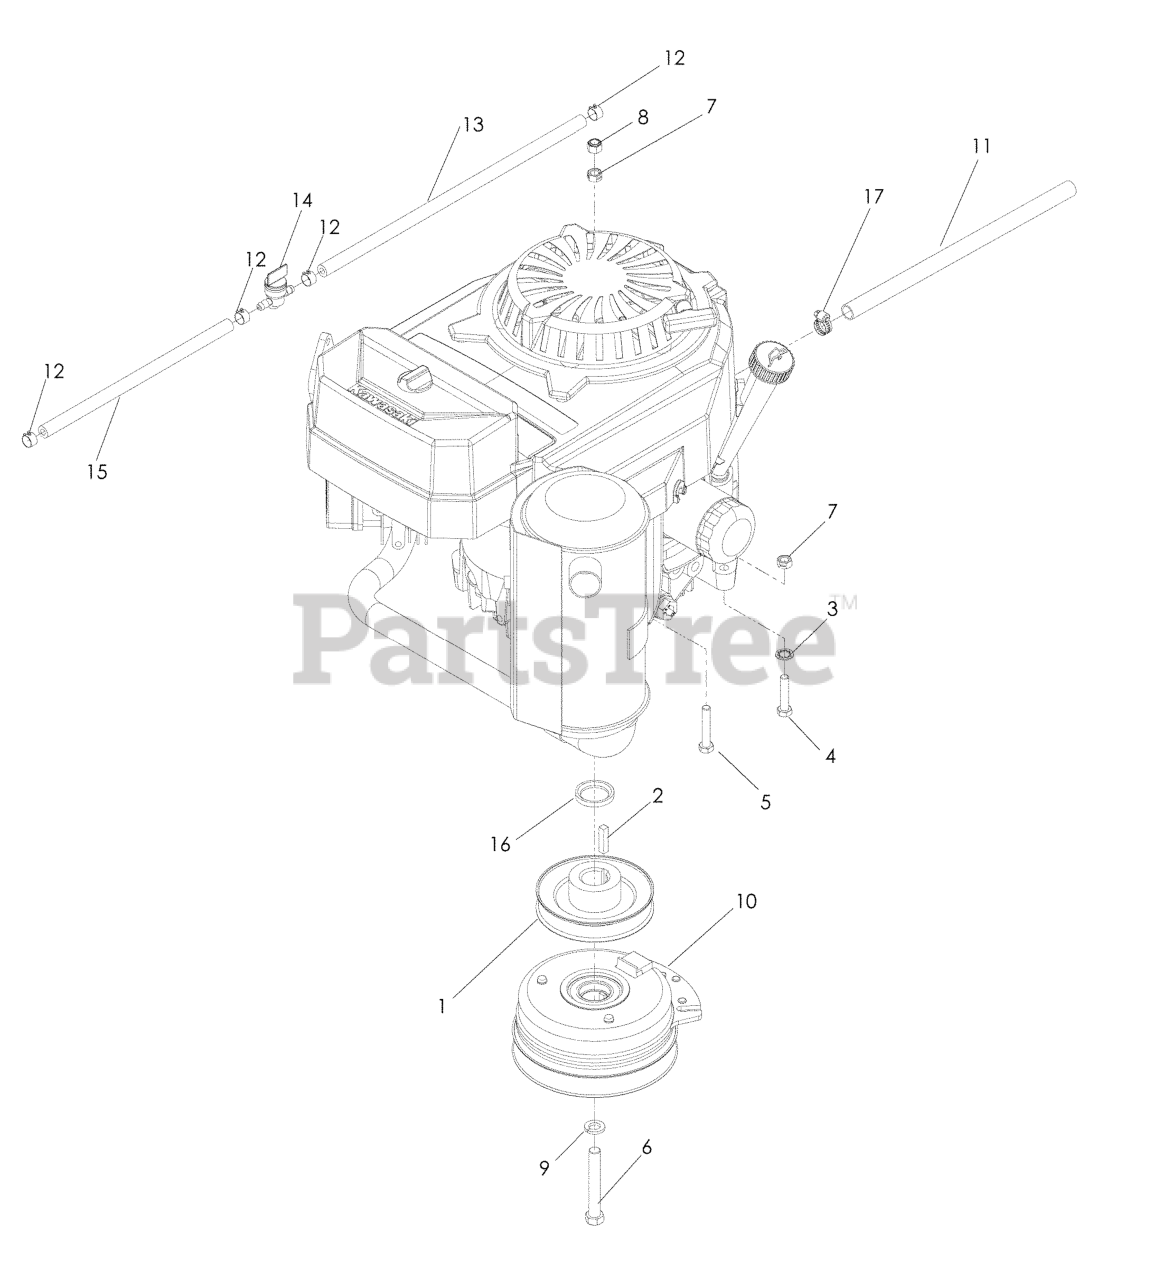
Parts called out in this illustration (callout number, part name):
2	KEY 1/4 SQ X 1 1/8
3	WASHER, 3/8 ITLW ZN
4	CAPSCREW 5/16 X 1/1/2 HEX HEAD
5	HCS 5/16C X 1 3/4
6	HEX SCREW 7/16-20 X 3
7	NUT 5/16C CENTERLOCK
8	NUT 5/16 NYLOC
9	WASHER 7/16 LOCK
10	CLUTCH 125 FT/LB
11	OIL DRAIN HOSE
12	HOSE CLAMP
13	FUEL LINE 14"
14	FUEL VALVE
15	GAS LINE 10"
17	HOSE CLAMP T-1865
